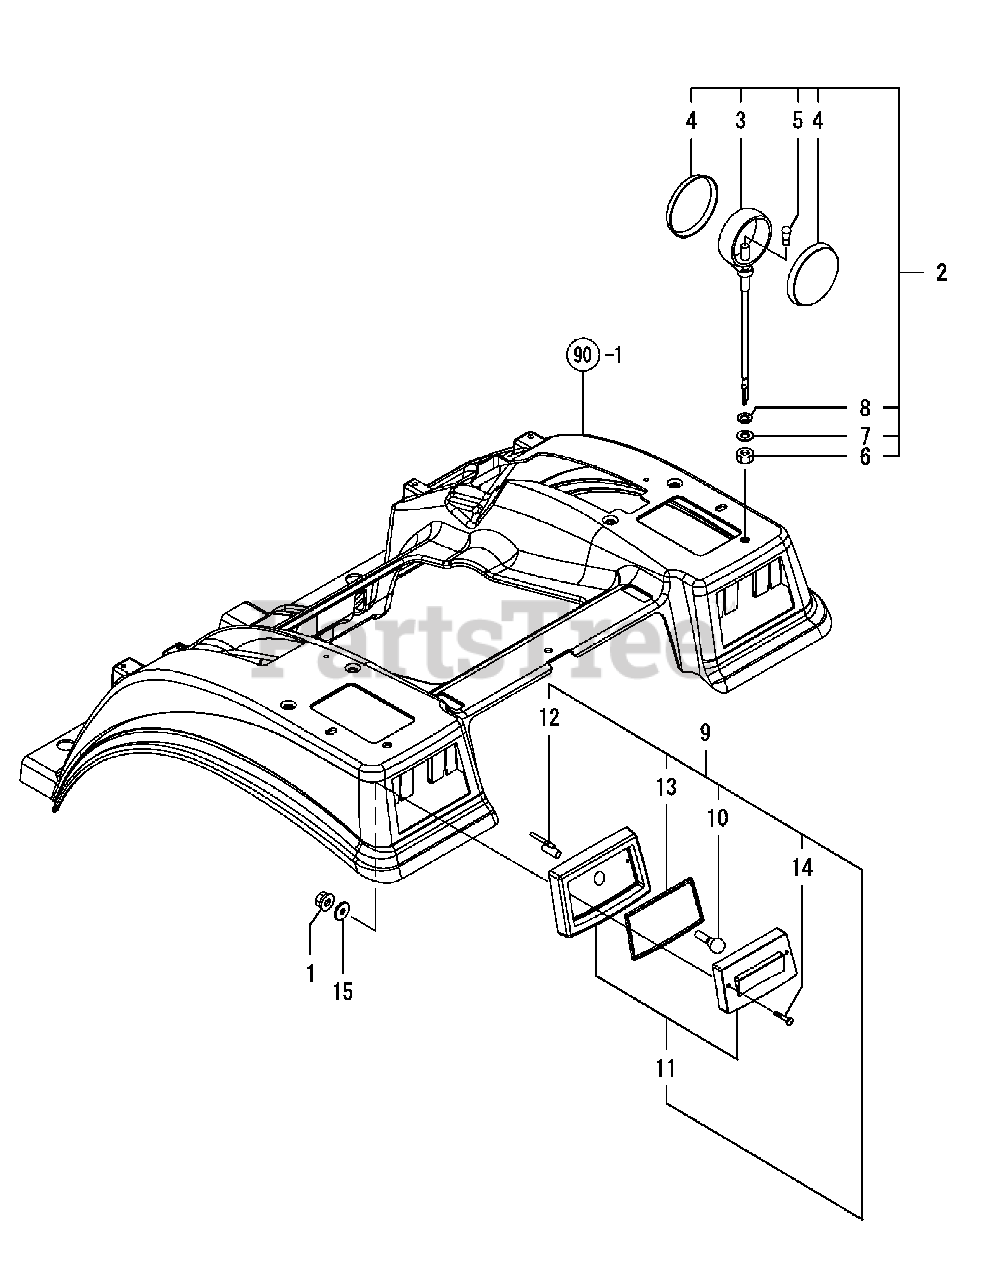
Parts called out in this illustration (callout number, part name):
1	NUT W/WASHER 6
2	LAMP ASSY, FLASHER
8	WASHER, SPRING 13
10	BULB 12V-21/5W
12	HOUSING SEMI ASSY
